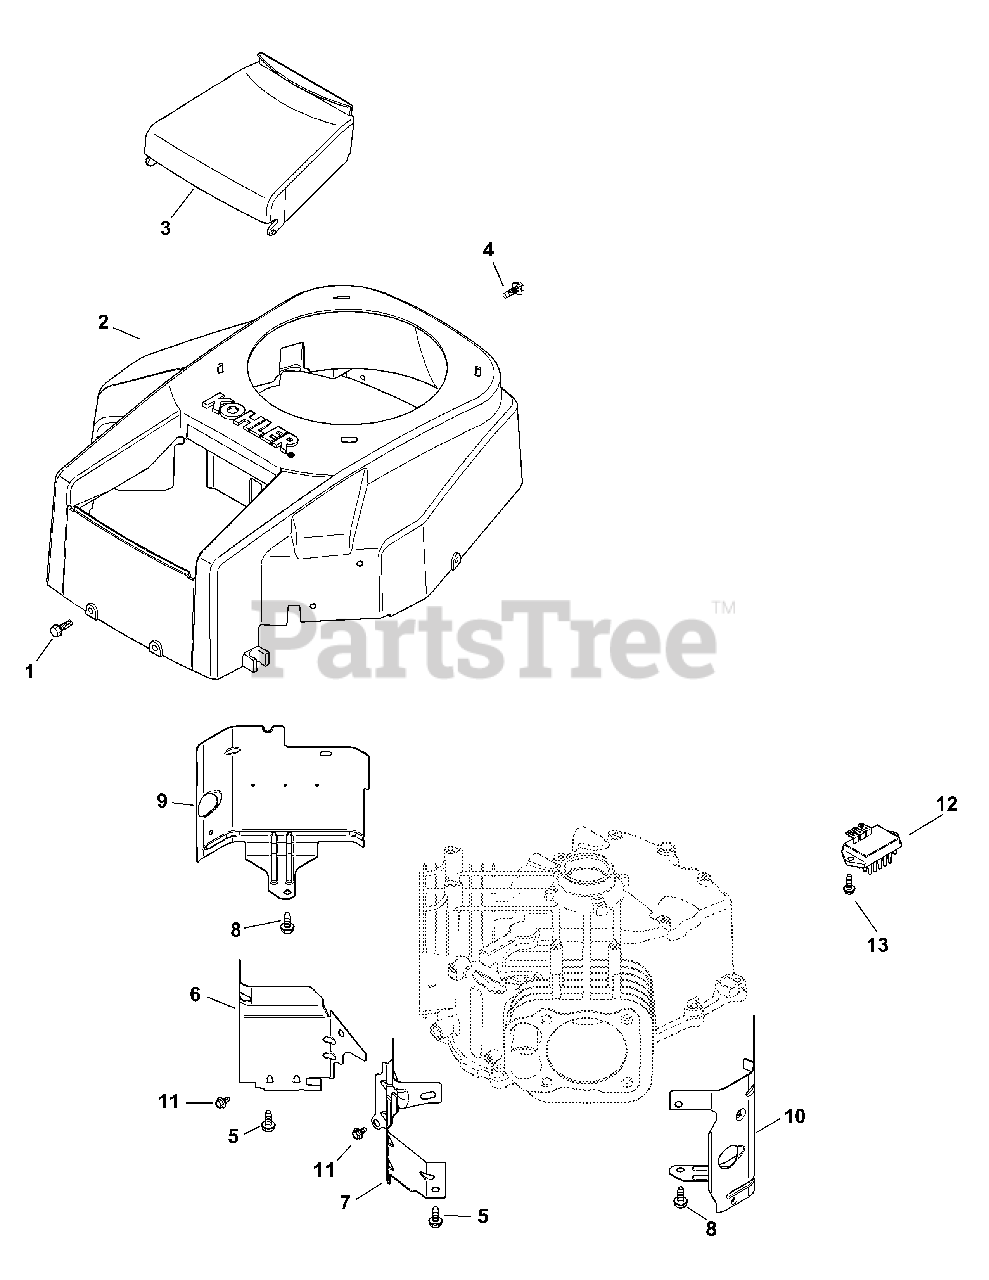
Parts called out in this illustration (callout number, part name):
1	Tap Screw, M6 x 1.7 x 18
2	Housing Blower Kit
3	Air Cleaner Cover
4	Flg. Thd. Frm. Screw, M5 x 0.8 x 16
5	Flg. Thd. Frm. Screw, M6 x 1.0 x 16
6	Valley Baffle - #1 Cylinder
7	Valley Baffle - #2 Cylinder
8	Flng. Thd. Frm. Screw, M6 x 1.0 x 10
9	Cyl Barrel Baffle - #1 Side
10	Cyl Barrel Baffle - #2 Side
11	Flg. Thd. Frm. Screw, M5 x .8 x 10
12	Regulator/Rectifier
13	Flg. Thd. Frm. Screw, M5 x .8 x 20
